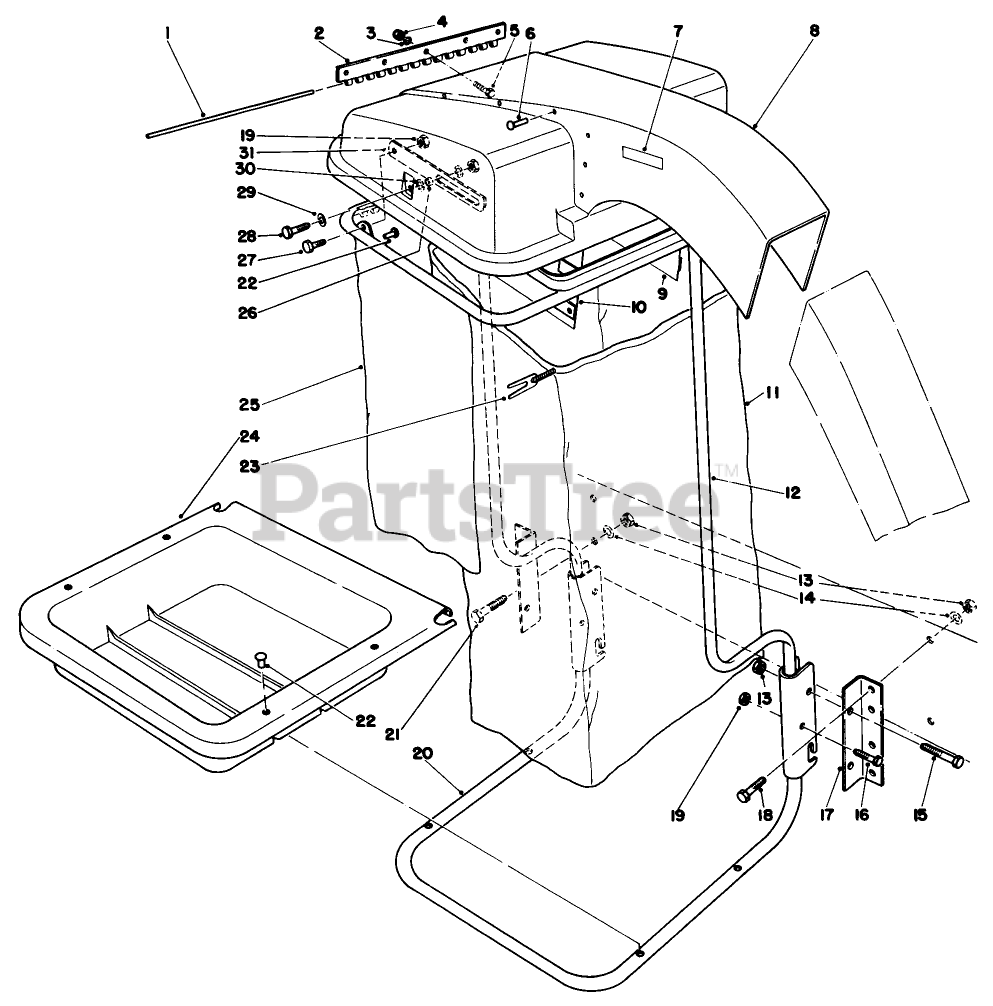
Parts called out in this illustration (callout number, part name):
1	HOOD HINGE PIN
2	Hinge Half
3	WASHER-FLAT
4	NUT-LOCK, NI
6	RIVET-BLIND
7	Decal-Caution
8	Hood Assembly (Incl. Ref. #2-7 & 9-10)
9	Screen Left Hand
10	Screen Right Hand
11	BAG-CLOTH, 32"
12	Support Tube Assembly-Upper (Incl. Ref. #22 & 25)
13	NUT-LOCK, CONE
14	WASHER-FLAT
15	SCREW-HH
16	SCREW-HH
17	BRKT-FRAME B
18	SCREW-HH
19	NUT-LOCK, CONE
20	Support Tube Assembly-Lower (Incl. Ref. #22 & 24)
21	SCREW-HH
23	BAG CORD FASTENER
24	Tray-Lower
25	Skirt-Bagging Frame
26	SPACER - PIVOT ARM
27	SCREW-HH
28	SCREW-HH
29	WASHER-FLAT
30	WASHER-FLAT
31	Stop-Hood
